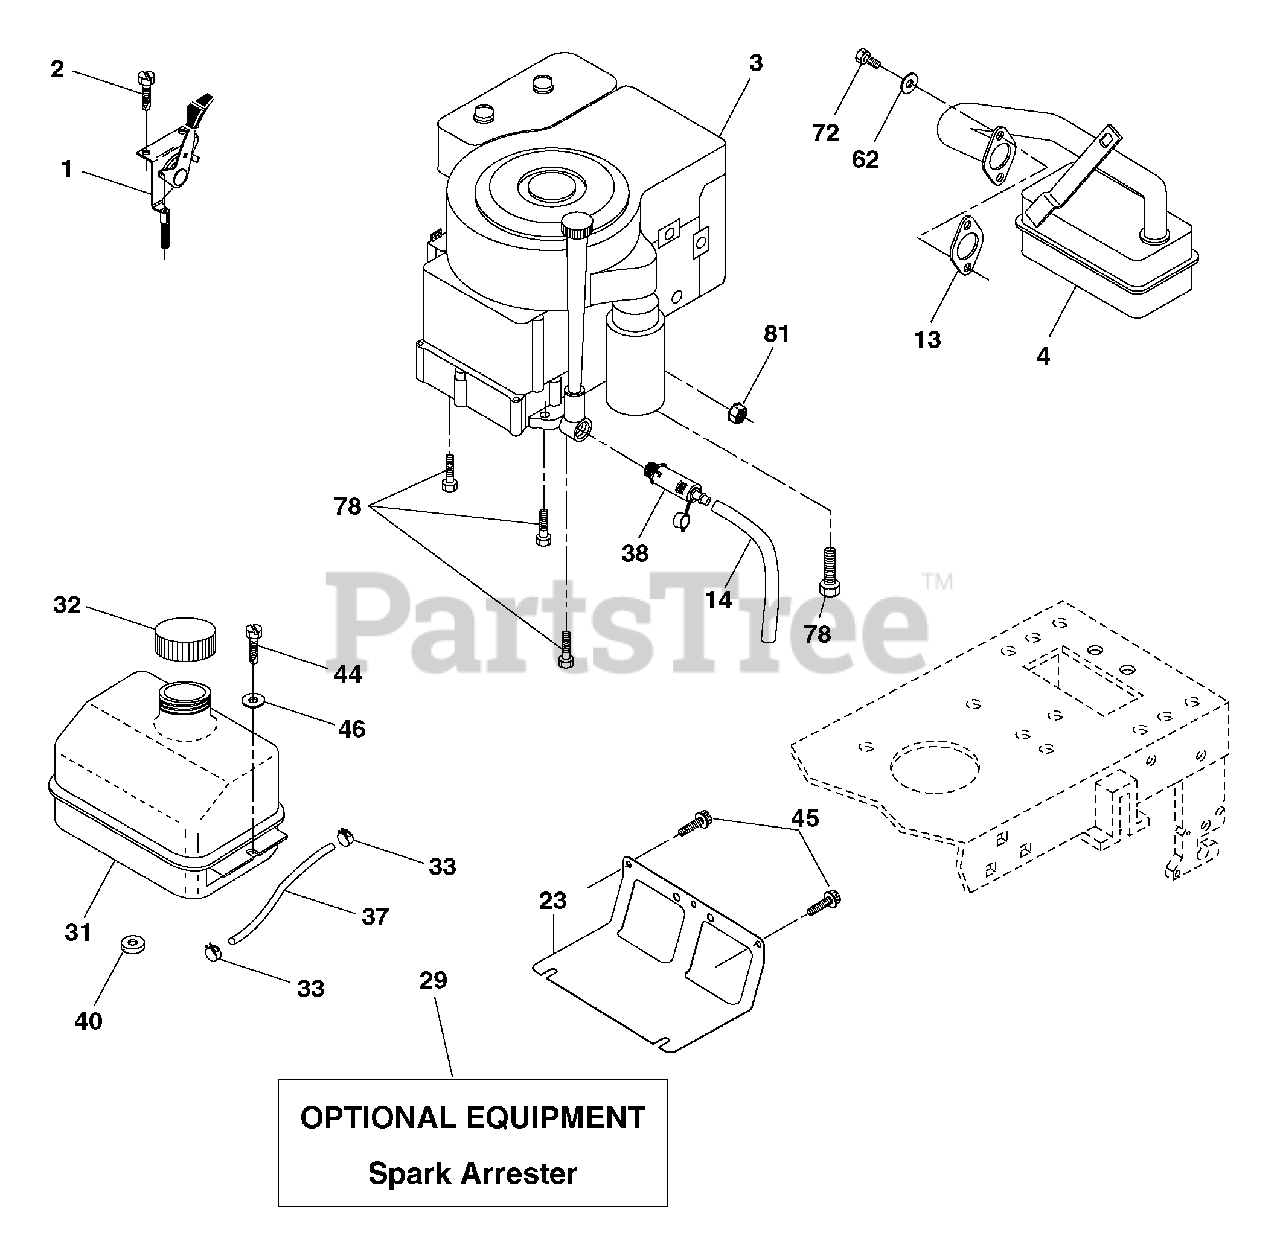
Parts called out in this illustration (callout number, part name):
1	Control Th/ch Flag
2	Screw Hex Thd Cut 1/4-20 x 1/2
4	Muffl er Exhaust B&S
13	Gasket Eng 1 313 Id Tin Plated
14	Tube Drain Oil Easy
23	Shield BRN/DBR Guard
29	Kit Spark Arrestor (Flat Scrn)
31	Tank Fuel Front
32	Cap Asm Fuel
33	Clamp Hose
37	Line Fuel 20"
38	Plug Drain Oil
40	Bushing Snap Nyl Blk Fuel Line
44	Screw Thdrol 1/4-20 x 3/4
45	Screw Hex Wsh Thdrol 3/8-16
46	Washer 9/32 x 7/8 x 16 Ga.
62	Washer Split
72	Screw Socket Head 5/16-18 x 3/4
78	Screw 3/8-16 x 1-1/4
81	Nut Keps Hex 1/4-20 unc
